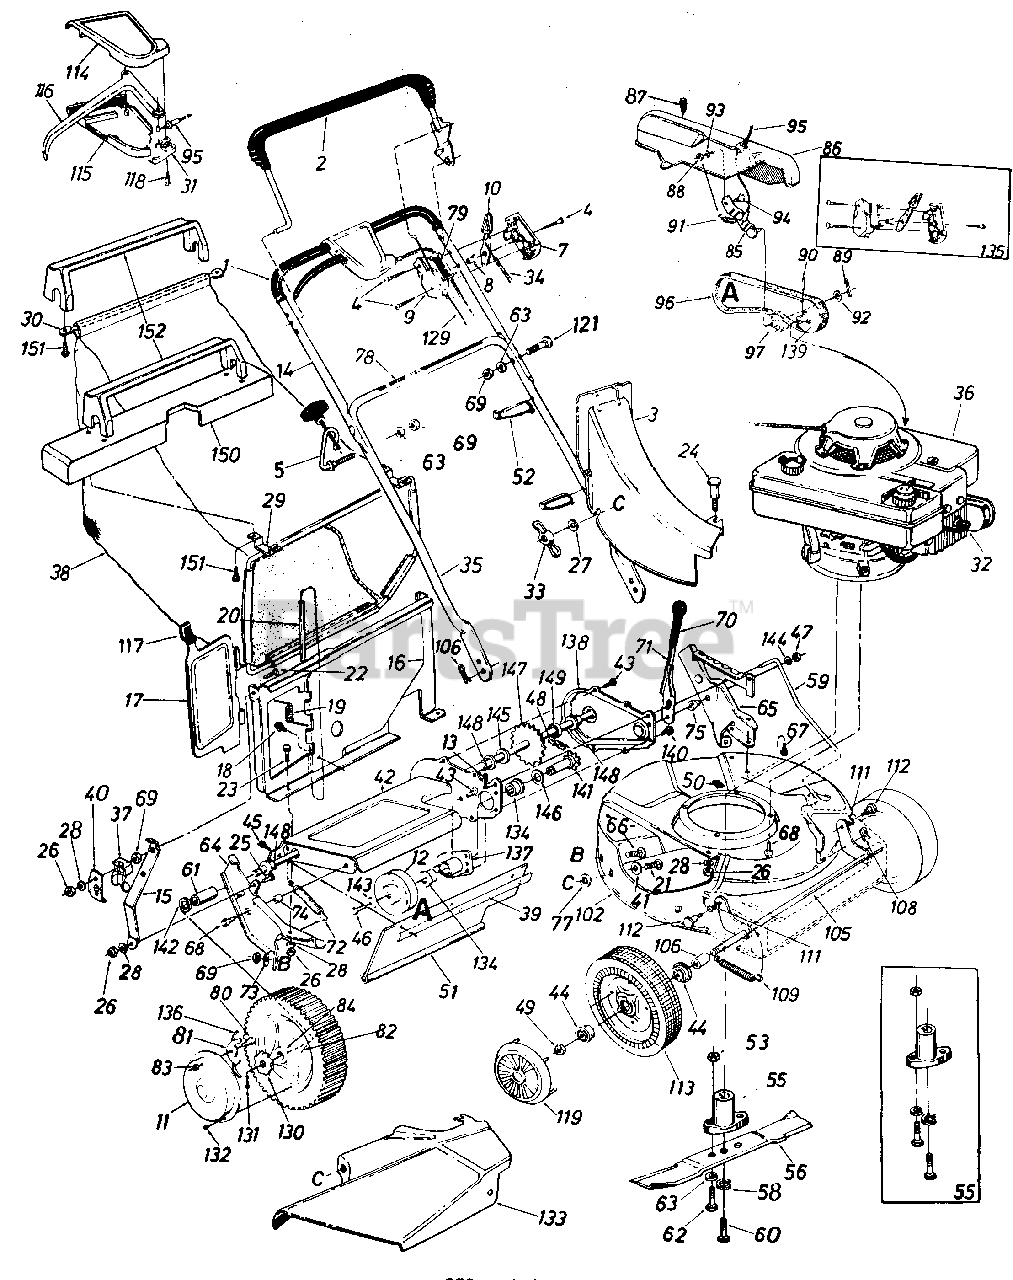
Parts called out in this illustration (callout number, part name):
2	Control Handle Ass'y. L.H.
3	Top Discharge Chute Ass'y.
4	Truss Mach. Scr. #12 x 1.50" Lg.
5	Rope Guide Bolt
7	Control Panel Half
8	Control Disc Pin
9	Clutch Panel Half
10	Throttle Control Lever
11	Hub Cap
12	1/2 V-Pulley
13	Cotter Pin 3/32" Dia. x .75"
14	Upper Handle Chrome
15	Panel Support Brkt.
16	Top Catcher Panel
17	Top Doort
18	Hex B-Tap Scr. #10 x .38"
19	Torsion Spring
20	Pivot Pint
21	Carriage Bolt 1/4-20 x .62"
22	Truss Mach. Scr. 1/4-20 x 1.0" Lg.
23	Hex Bolt 1/4-20 x .50" Lg.
24	Shoulder Bolt .312 Dia. x .18 Lg. Special
25	Hex Bolt 1/4-20 x .62" Lg.
26	Hex Nut 1/4-20 Thd.
27	Fl-Wash. .280" I.D. x .620"
28	L-Wash. 1/4" I.D.
29	Front Grass Catcher Framet
30	Upper Bag Supportt
31	S.P. Control Cover
32	Spark Plug Insulator
33	Wing Nut
34	Throttle Control Wire 45"
35	Lower Handle Chrome
36	Engine
37	Rope Guide Half
38	21" Top Discharge Grass Bag
39	Retaining Strip
40	Rope Retainer Spring Clip
41	Fl-Wash. .344" I.D. x .62"
42	Chain Axle Ass'y.
43	Hex B-Tap Scr. 1/4" x .38" Lg.
44	Flange Ball Bearing 1/2" I.D.
45	Hex AB-Tap Scr. 1/4 x .62"
46	Hex Wash. TT-Tap Scr. 1/4-20
47	Hex Patch L-Nut 3/8-24 Thd.
48	#48 Chain .500" Pitch x .30 Links
49	Hex L-Nut 1/2-20 Thd.
51	Rear Flap 3.75" x 17.30" Lg.
52	Cable Tie
53	Hex Nut 5/16-24 Thd.
55	Blade Adapter Kit
56	21" Blade
58	L-Wash. 3/8" I.D. H.D.
59	Height Adj. Rod 19.42" Lg.
60	Hex Bolt 3/8-24 x 2.25" Lg. (Grade 5)
61	Spacer .51" I.D. x .69" O.D. x.69" Lg.
62	Hex Bolt 5/16-24 x 1.00" Lg. (Grade 5)
63	L-Wash. 5/16" I.D.
64	R.H. Handle Wheel Brkt. Ass'y.
65	L.H. Handle Wheel Brkt. Ass'y.
66	Carriage Bolt 5/16-18 x .62"
67	Hex Wash. Hd. B-Tap Scr. 5/16-18
68	Hex Wash. Hd. TT-Tap Scr. 3/8-16
69	Hex Nut 5/16-18 Thd.
71	Height Adj. Lever
72	Extension Spring .50" O.D. x 3.80" Lg.
73	Bell-Wash. 5/16" I.D.
74	Spacer .385" I.D. x .502" O.D. x .270" Lg.
75	Shld. Spacer .500" Dia. x .100
77	Bolt Retainer 1/4 x .50" O.D.
78	Instruction Label
79	Control Label
80	Shld. Scr. .342" Dia. x .268
81	Pawl
82	Wheel Ass'y. Comp. Rear 8x 1.75
83	Hex Ins. L-Nut 1/4-20 Thd.
84	Flange Ball Bearing 1/2" I.D.
85	Belt Idler Bracket Ass'y.
86	Belt Cover
87	Hex Wash. S-Tap Scr. 1/4-20 x.50" Lg.
88	Hex Nut 1/4-20 Thd.
89	Cotter Pin 1/8" Dia. x 1.00" Lg.
90	Spring Pin Spir. 3/16" Dia. x 1.00" Lg.
91	Extension Spring .33" O.D. x 1.12" Lg.
92	Fl-Wash. .531" I.D. x .930" O.D. x .050
93	L-Wash. 1/4" I.D.
94	Shld. Bolt .375" Dia. x .181
95	S.P. Cable x 53.0" Lg.
96	"V"-Belt 1/2 " x 32.0" Lg.
97	Fl-Idler Plastic 1.62" Dia.
106	Sleeve .526" I.D. x .690" O.D. x .880" Lg.
108	Intern. Cotter Pin 5/16" Dia.
109	Extension Spring .50" O.D. x 3.20" Lg.
111	Intern. L-Wash. 3/8 I.D.
112	Shld. Bolt .623" Dia. x .425
113	Front-Wheel Ass'y. Comp. 7x 1.50
114	Self-Propelled Control Cover
115	Self-Propelled Control Cover
116	Control Lever
117	Door Grip
118	Fl-"C"-Sunk Hd. Tap Scr. #10 x .75" Lg.
119	Hub Cap Plastic
121	Curved Carr. Bolt 5/16-18 x 1.38" Lg.
129	Control Cable 55" Lg.
130	Ratchet Wheel 1.62" O.D.
131	Cotter Pin 1/8" Dia. x 1.00" Lg.
132	Pan Hd. Tap Scr. #12 x .50" Lg.
133	Side Chute Deflector Ass'y.
134	Flange Bushing
135	Kit Control Housing Comp.
136	Spring Nylon
137	Bearing Hub Flange Ass'y.
138	Chain Cover
139	Engine Pulley 1/2"
140	Hex Wash. S-Tap Scr. 1/4-20 x.50" Lg.
141	Sprocket Shaft Ass'y.
142	Fl-Wash. .531" I.D. x .93" O.D.
143	Bell-Wash. .265" I.D. x .75" O.D.
144	Fl-Wash. .385" I.D. x .87" 0. D.
145	Fl-Wash. .51" I.D. x 1.0" O.D.
146	Fl-Wash. .62" I.D. x 1.12" O.D.
147	Rear Shaft Ass'y. 22.05" Lg.
148	Hex Flange Bearing .506" I.D. Plastic
149	Spacer .510" I.D. x 1.00" O.D. x .210" Lg.
150	Catcher Frame Cover
151	Truss Mach. Tap Scr. 1" Lg.
152	Bag Handle
